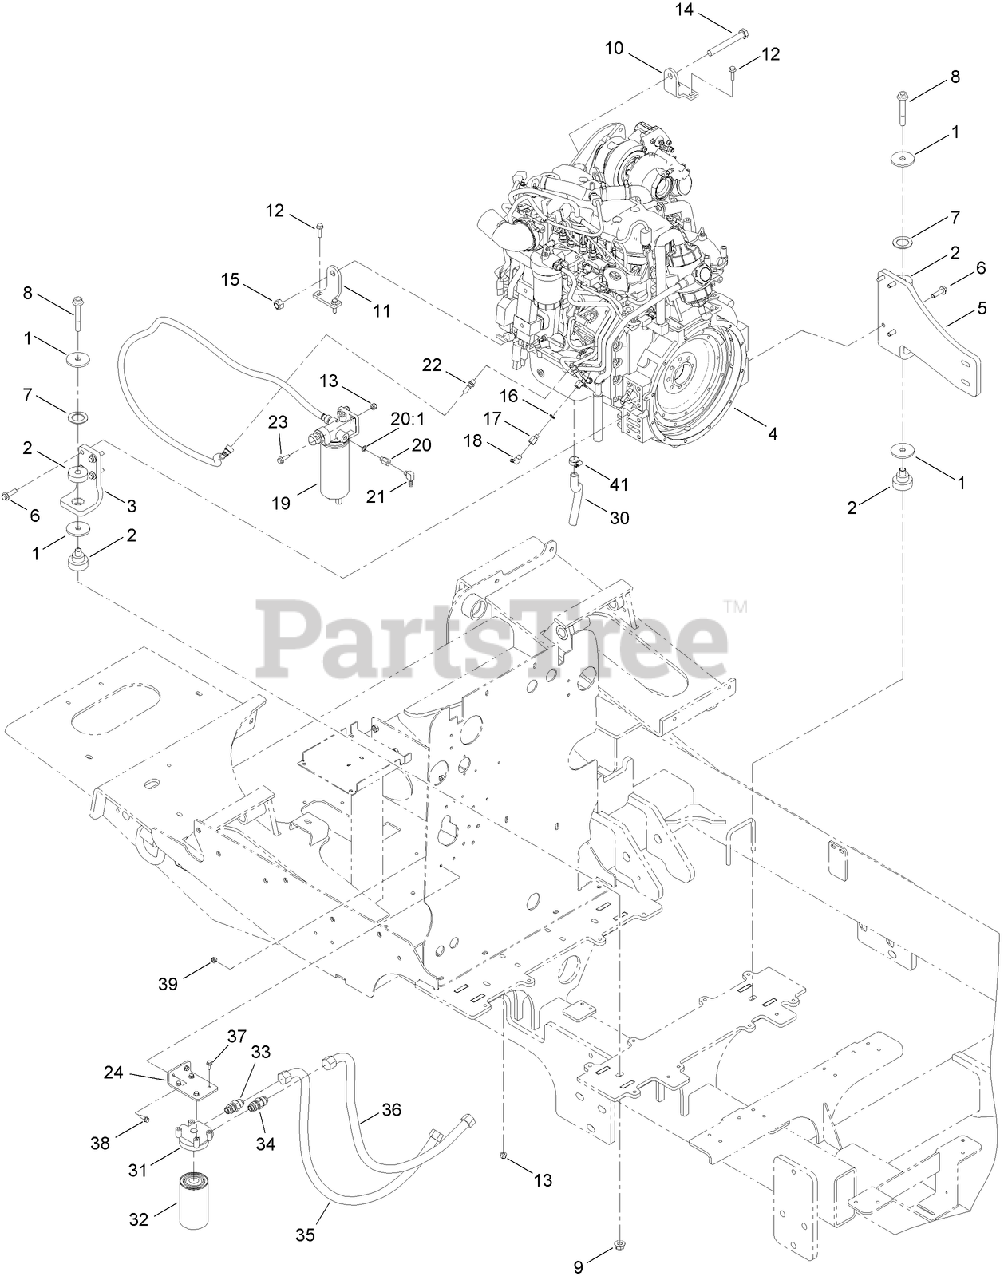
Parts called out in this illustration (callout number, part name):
1	WASHER
2	ISOLATOR-MOUNT, UNIVERSAL
3	MOUNT-ENGINE, FRONT (RH)
4	ENGINE-QSB4, TIER 4I
5	MOUNT-ENGINE, FRONT (LH)
6	SCREW-HHF
7	SPACER-ISOLATOR
8	SCREW-FLANGE
9	NUT-HHF
10	MOUNT-ENGINE
11	MOUNT-ENGINE
12	SCREW-HHF
13	NUT-LOCK, NI
14	SCREW-HH
15	NUT-LOCK
16	SEAL-FITTING, FUEL
17	FITTING-REDUCER
18	FITTING-ELBOW, 90
19	FUEL FILTER ASM
20	FITTING-REDUCER
20:1	SEAL-FITTING, FUEL
21	FITTING-ELBOW, 90
22	FITTING-FUEL
23	SCREW-HHF
24	PLATE-MOUNTING, FILTER
30	HOSE-DRAIN, OIL
31	HEAD-FILTER, OIL
32	FILTER-OIL
33	FITTING-OIL
34	FITTING-OIL
35	HOSE-OIL
36	HOSE-OIL
37	SCREW-HHF
38	SCREW-HHF
39	NUT-LOCK, HHF
41	CLAMP-HOSE
